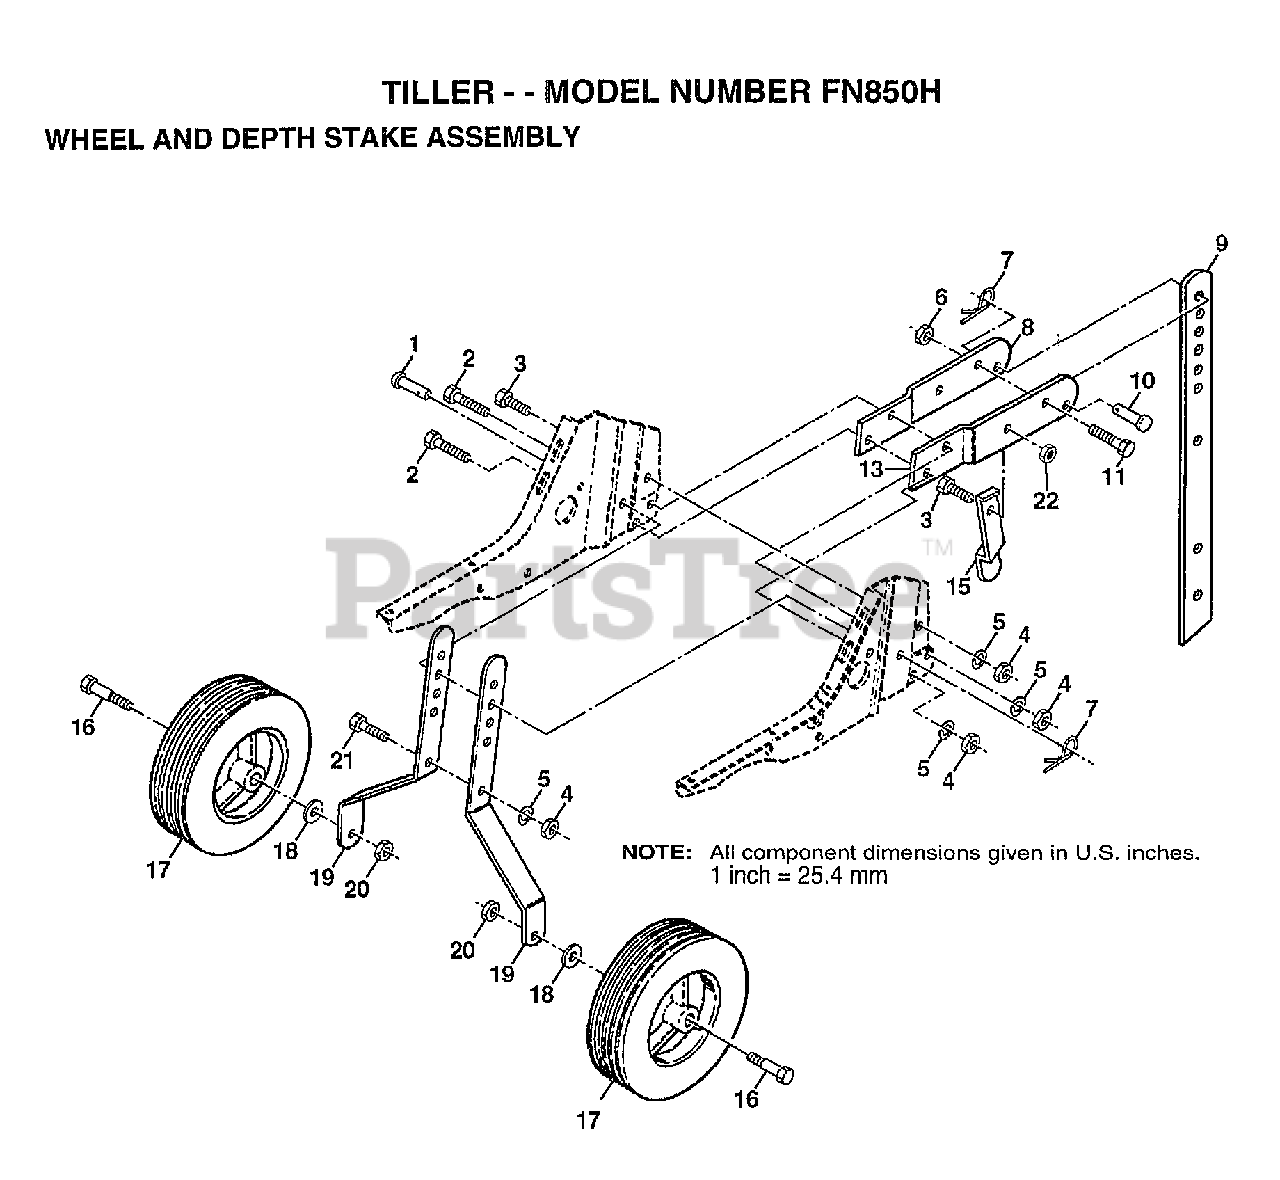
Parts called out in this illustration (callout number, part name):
1	DRILLED RIVET RT
3	BOLT
4	NUT.HEX.5/16-18
5	LOCKWASHER
6	NUT
7	SPRING.RETAINER
11	BOLT
15	STAKE SPRING TI
16	BOLT SHOULDER
18	WASHER
22	NUT
